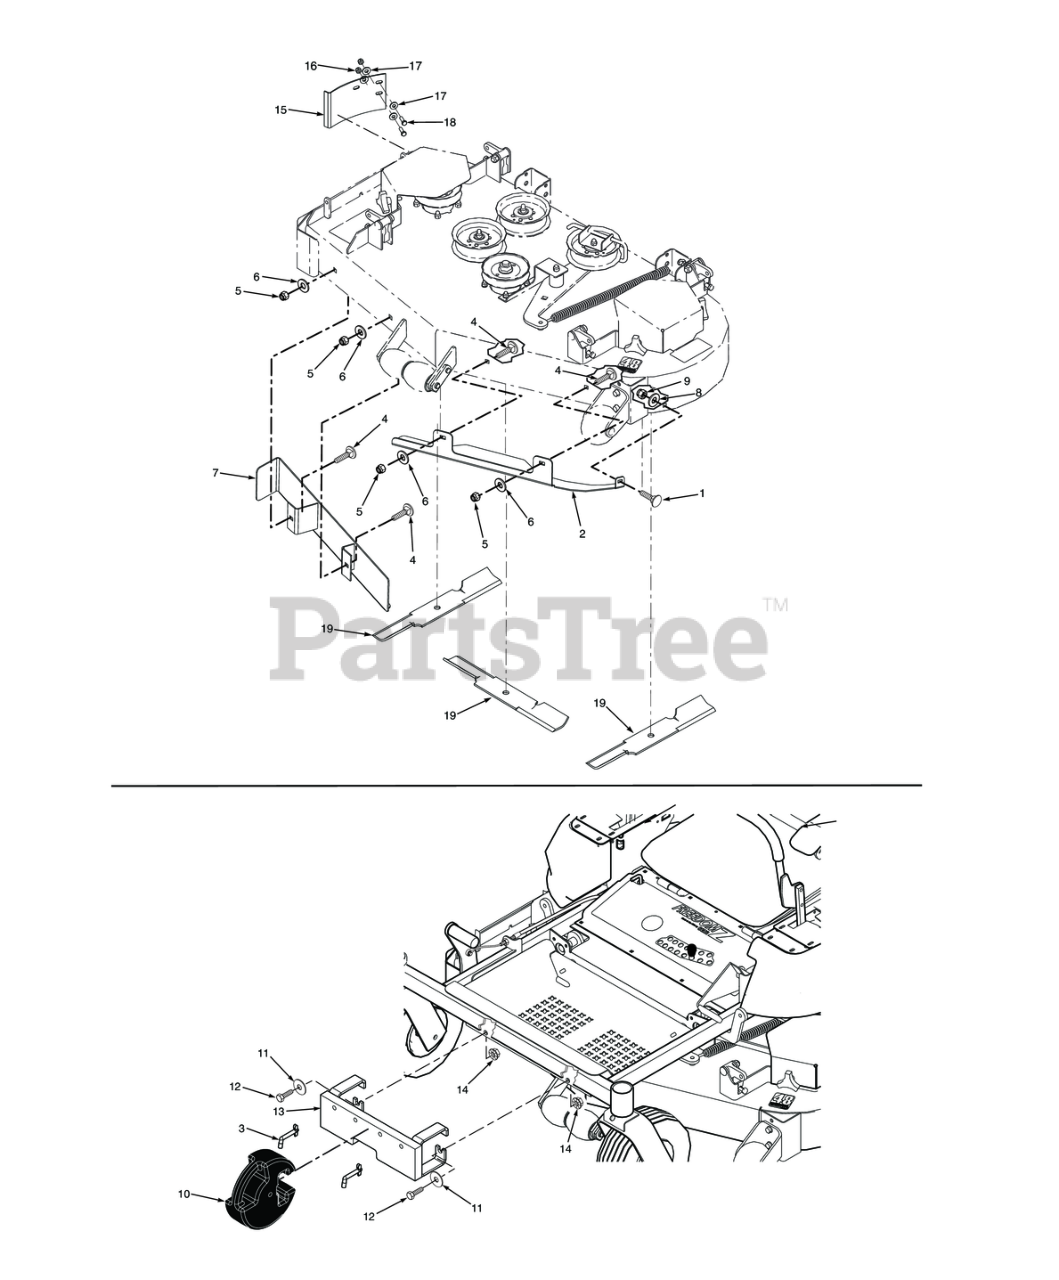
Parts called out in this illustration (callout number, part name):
1	Bolt, 5/16-18 x .75 RHSN Carriage
2	Baffle, LH - 52" Deck
3	Pin, Weight Retention
4	Carriage Bolt, 3/8-16 x 1.0"
5	HEX NUT, ELASTIC STOP LOCK, 3/8-16
6	Flat Washer, 1/2 (.562 x 1.375 x .109)
7	Baffle, Weldment, RH - 52" Deck
8	Flatwasher, 5/16-.344 x .688 x .065 (48V / 52V)
9	Nut, Center Lock, 5/16-18(32)
10	Weight
11	Flat Washer, 1/2 (.562 x 1.375 x .109)
12	Bolt, Hex Head 1/2-13 x 1-1/4"
13	Support Weldment, Weight Mounting
14	Nut, Hex Serrated Flange 1/2-13
15	Filler Plate - 52
16	HEX NUT, ELASTIC STOP LOCK, 5/16-18
17	Flatwasher, 5/16-.375 x .875 x .083 (35BV & 37BV-EFI)
18	Bolt, Heax Head 5/16-18 x 1" (48V / 52V)
19	Cutter Blade 18" Hi Lift (marbane)
